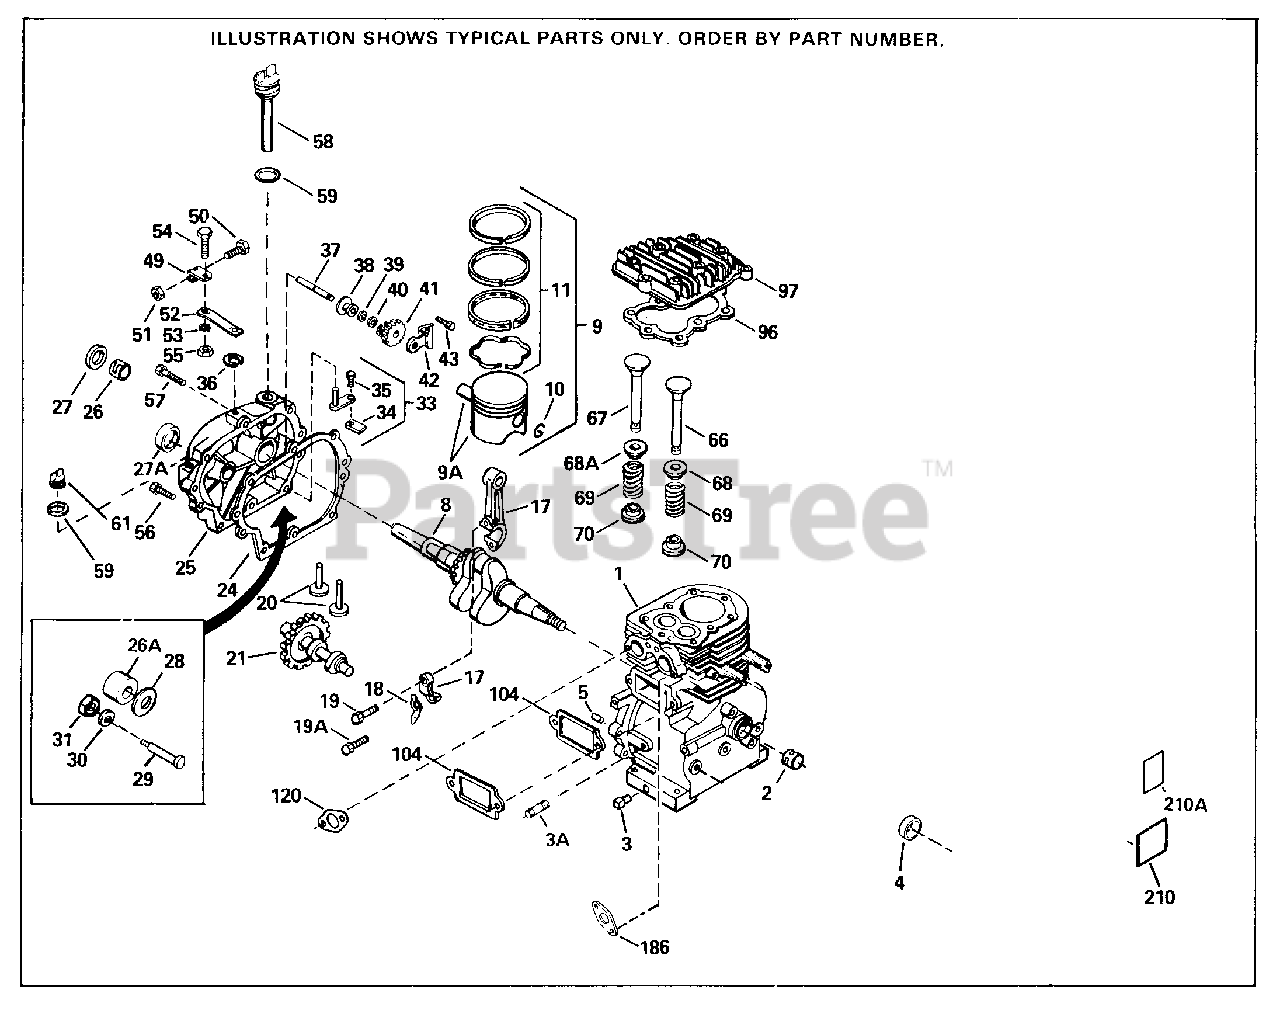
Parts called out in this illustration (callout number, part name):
1	"Cylinder (Cast Iron Liner)(3-5/16") ( Incl. 2, 20, 72, 72A & 72B) I Liner)
3	Oil Drain Plug (Sq. hd., 1/4-18)
3A	Plug, Pipe (Sq. hd., 1/8-27)
4	Oil Seal
5	Dowel Pin
8	Crankshaft
9	Piston, Pin & Ring Set (Std.) 3-5/16"
9	Piston, Pin & Ring Set (.010" OS)
9	Piston, Pin & Ring Set (.020" OS)
9A	Piston & Pin Ass'y. (.010") Incl. 10
9A	Piston & Pin Ass'y. (.020") Incl. 10
9A	Piston & Pin Ass'y. (Std.) (3-5/16") Incl. 10
10	Piston Pin Retaining Ring
11	Ring Set (Std.) (3-5/16" Bore)
11	Ring Set (.010" OS)
11	Ring Set (.020" OS)
17	Connecting Rod Ass'y. (Incl. 46,47,49 )19A)
18	Oil Dipper
19	Bolt, Connecting rod
19A	Bolt, Connecting rod
20	Lifter, Valve
21	Camshaft (MCR)
24	Gasket, Cylinder cover
25	Cylinder Cover (Incl. 71, 75 & 80)& 6 1)
26	Crankshaft Bushing
27	Oil Seal
33	Rod Assy., Governor (Incl. 34 & 35)
34	Yoke, Governor
35	Screw, 6-40 x 5/16"
36	Retaining Ring
37	Shaft, Governor
38	Spool, Governor
39	Washer, Flat
40	Retaining Ring
41	Governor Gear Ass'y. (Incl. 81)
42	Bracket, Governor gear
43	Screw, 10-24 x 1/2"
49	Governor Lever Clamp
50	Screw, 10-32 x 3/4"
51	Lock Nut, 10-32
52	Lever, Governor
53	Lock Washer #8
54	Screw, 8-32 x 5/16"
55	Lock Nut, 8-32
56	Screw, 1/4-20 x 1-11/16"
57	Screw, 1/4-20 x 1-3/16"
58	Dipstick (Incl. 59)
59	Oil Fill Plug Gasket
61	Oil Fill Plug (Incl. 312) also availa ble in Packaged Part #740079
66	Exhaust Valve (Std.)(Incl. 151)
66	Exhaust Valve (1/32" OS) (Incl. 151)
67	Intake Valve (Std.) (Incl. 70)
67	Intake Valve (1/32" OS) (Incl. 70)
68	Valve Spring Cap
68A	Seal Assy., Intake valve
69	Valve Spring
70	Cap, Lower valve spring
96	Gasket Cylinder head
97	Cylinder Head Not included with short block
104	Valve Cover Gasket
120	Intake Pipe Gasket
186	Gasket, Exhaust
210	Decal, Instruction
